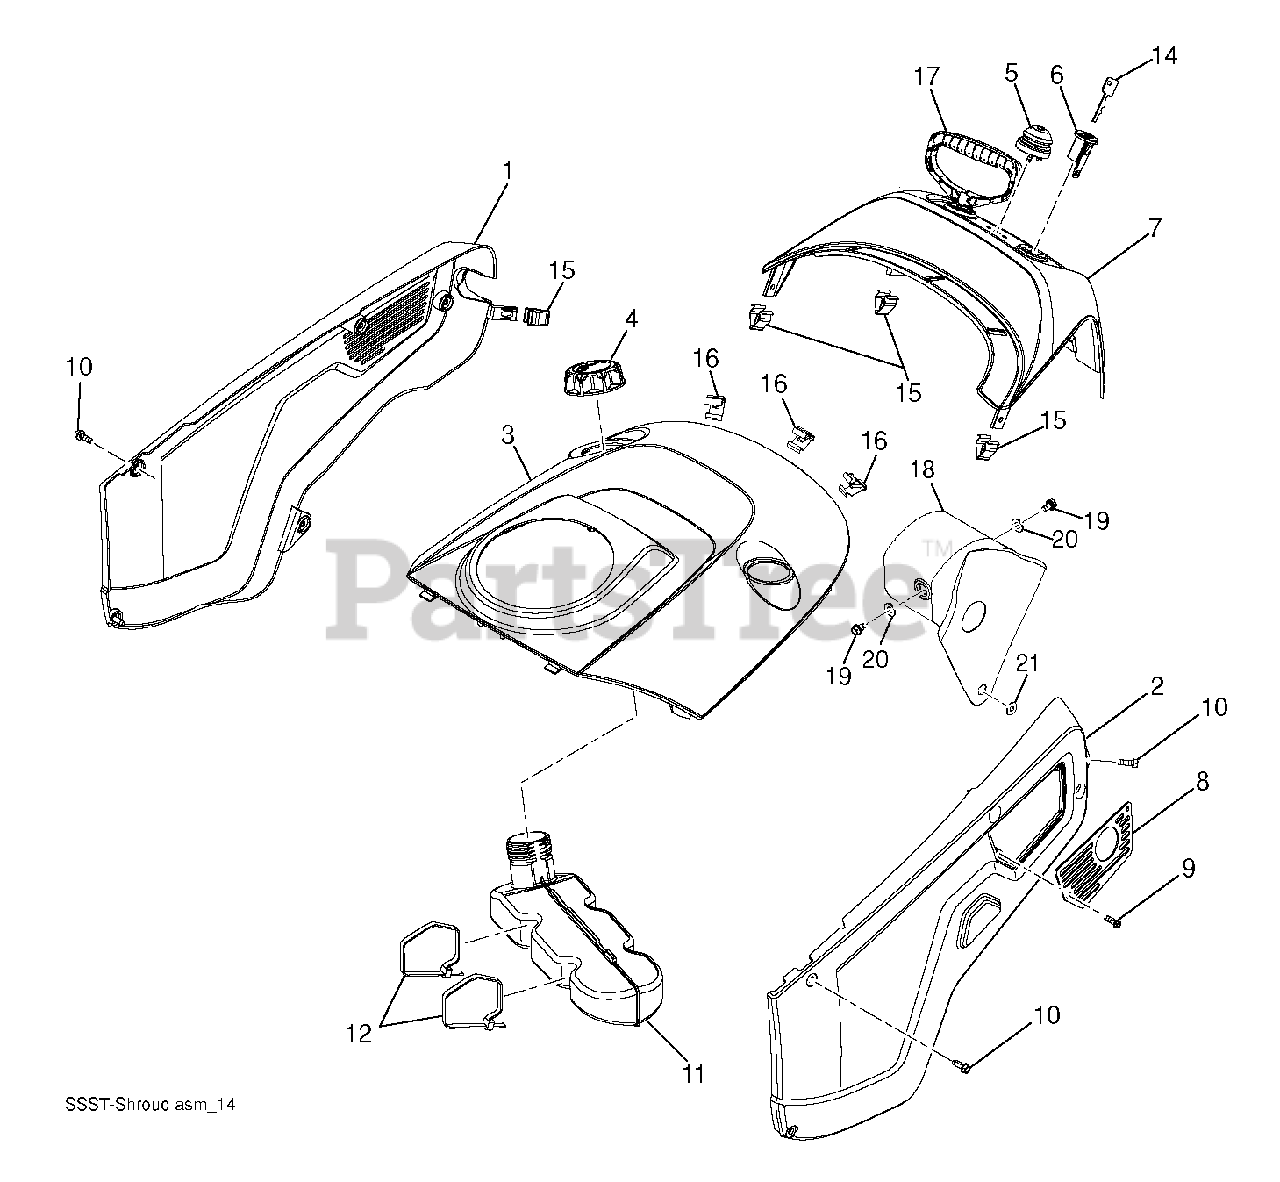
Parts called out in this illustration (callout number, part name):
4	CAP ASM.FUEL.2.25"FR.
5	RP BULB.PRIMER
6	KEY HOUSING
7	TOP.REAR.COVER
8	PLATE.EXHAUST.PNT.
9	SCREW.HX.13X.750
10	SCREW.PAN.HD.TORX.1/4-20X.750
11	TANK.FUEL.ASM
12	TIE.CABLE.24.5X.29.NYLON.WHITE
14	KEY
17	RP HANDLE.STARTER
18	COVER.MUFFLER.136CC/208CC.LCT
19	BOLT.M6-1.0X16MM
20	WASHER
